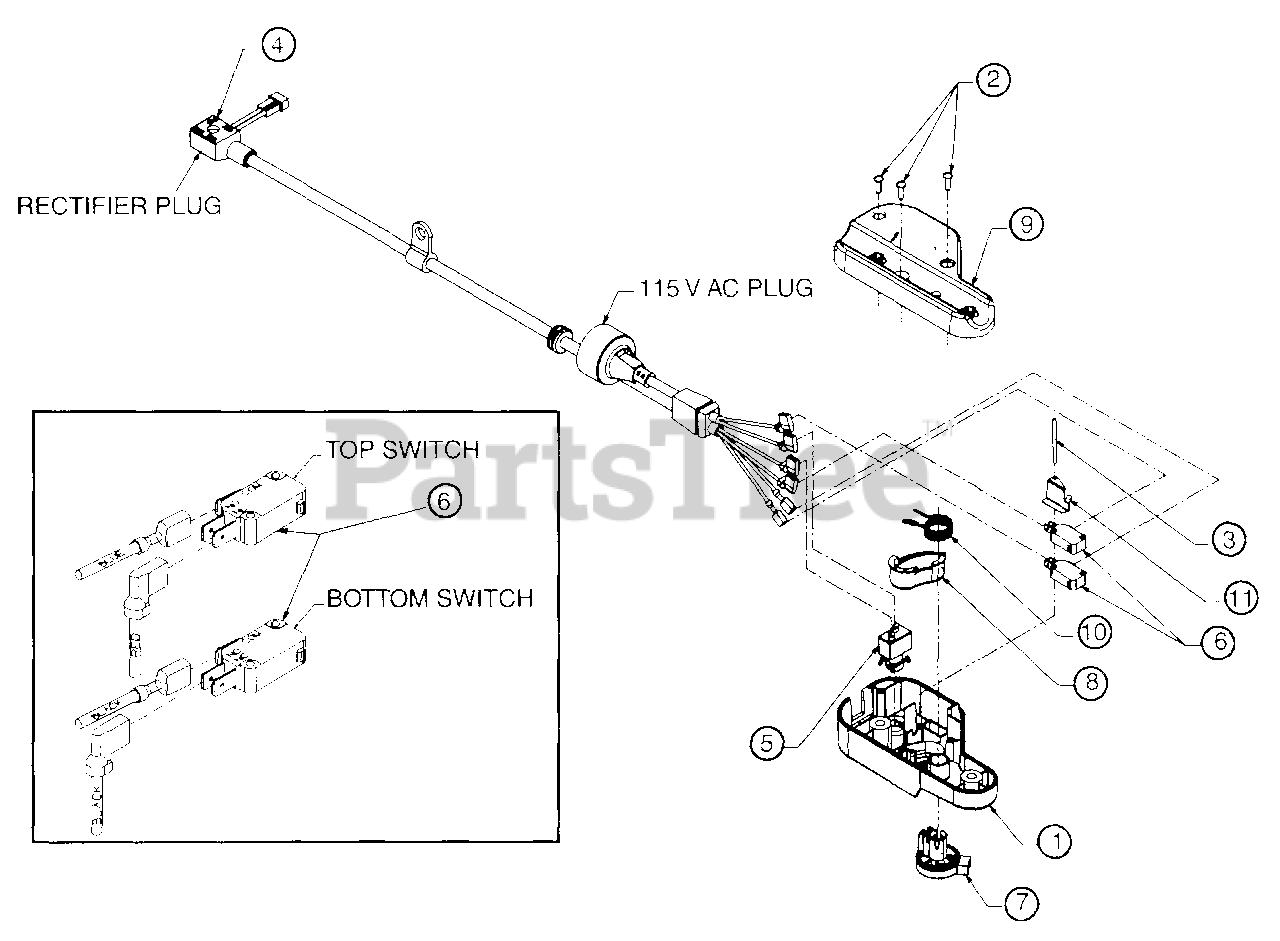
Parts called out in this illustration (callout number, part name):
1	Switch Hsg. Ass'y. (L.H.)
2	Drive Screw #8 x 1/2 Lg.
4	Cord, 115V volt w/plug
5	Circuit Breaker 120 volt 15 amp.
6	Switch, Micro 20 amp.
7	Clip, Bail Lock
8	Button, Bail Lock
9	Switch Housing (R.H.)
10	Torsion Spring
11	Actuator Arm
